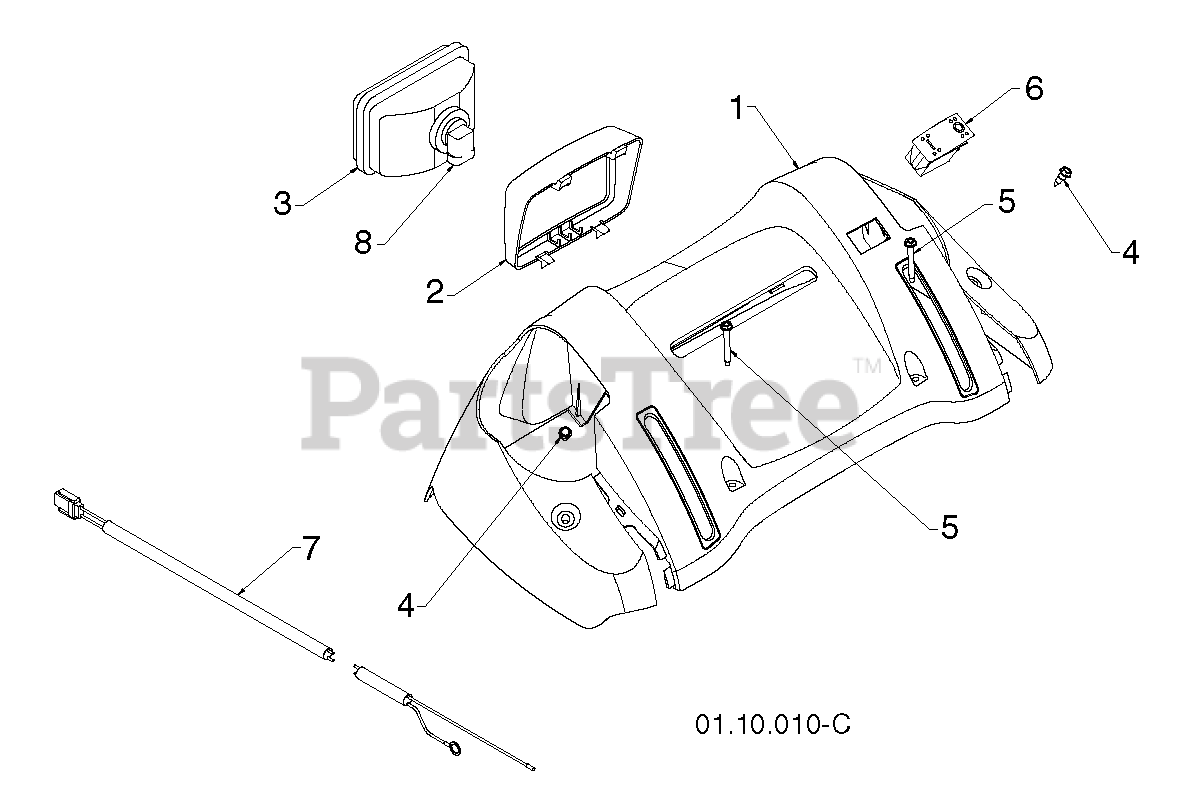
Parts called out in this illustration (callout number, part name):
1	PANEL.CONSOLE.
2	BEZEL.HEADLIGHT
3	HEADLIGHT.HALOGEN.SNOW
4	SCREW, HEX HEAD, TAPPING
5	SCREW, HEX HD TAPPING #10-24 1
6	SWITCH.HEATED.GRIP
7	WIRE HARNESS
8	BULB.HEADLIGHT.HALOGEN.
